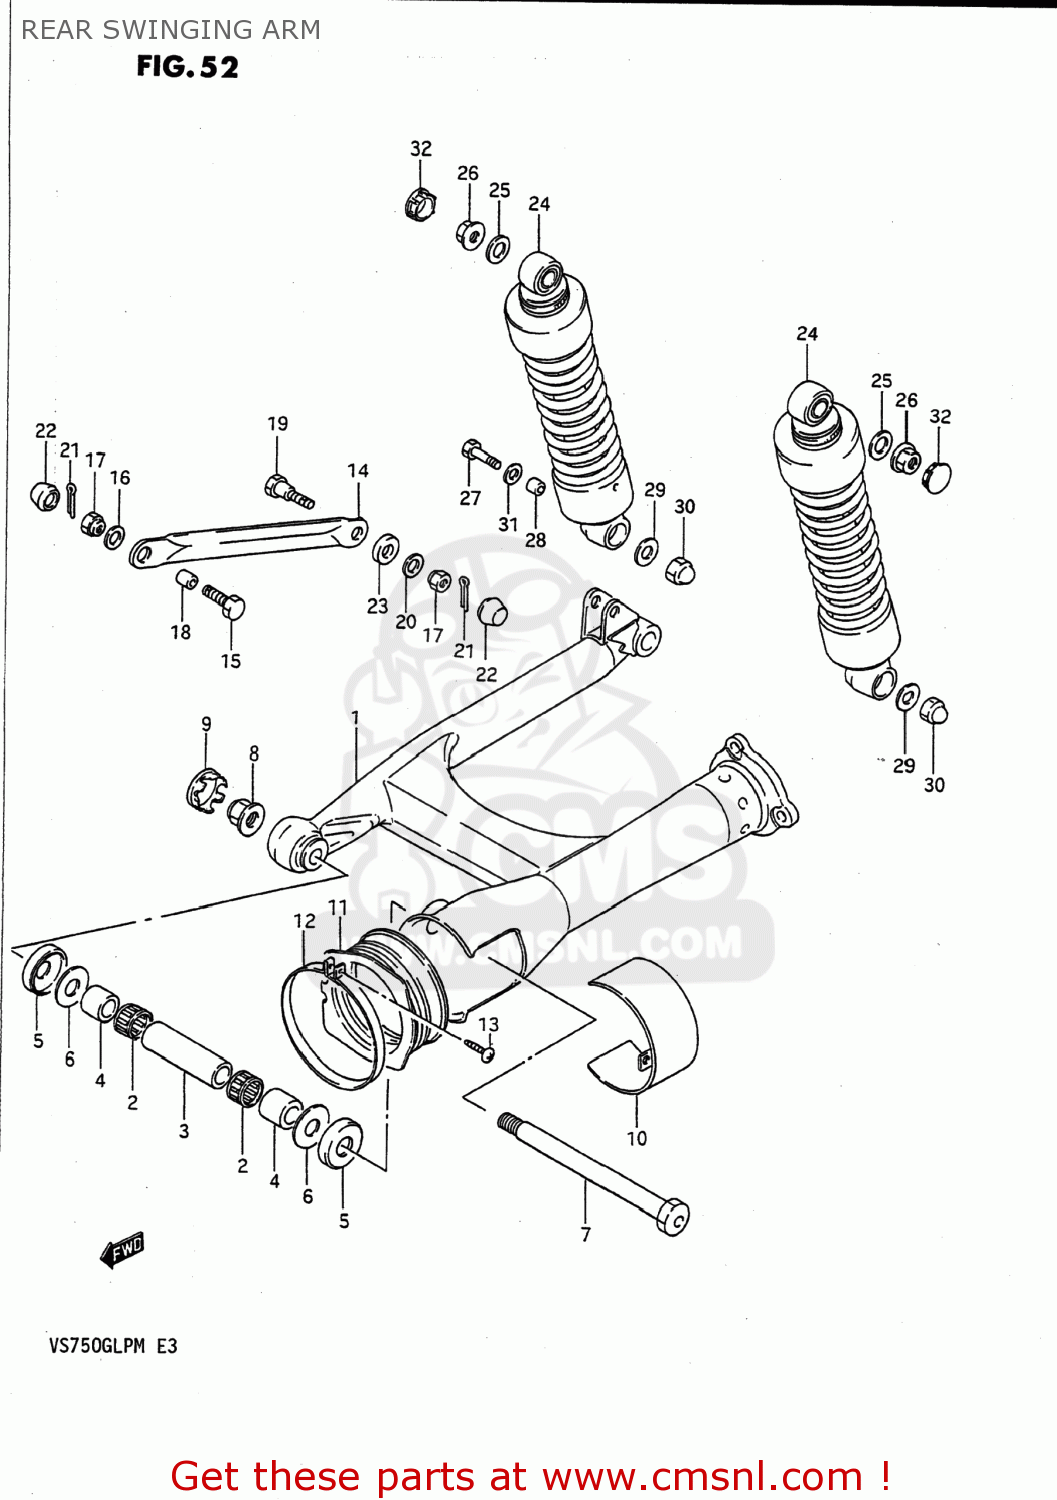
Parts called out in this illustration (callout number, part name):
1	SWING ARM COMP,REAR
2	BEARING(22X29X20)
3	SPACER,REAR SWING ARM PIVOT
4	SPACER,RR SWGARM PIVOT
5	CVR,RR SWGARM DUST SEAL(OD:40)
6	WASHER
7	SHAFT,RR SWINGINGARM PIVOT
8	NUT
9	CAP,RR SWINGING ARM PIVOT,R
10	COVER,REAR SWING ARM PIVOT
11	BOOT,PROPELLER SHAFT
12	CLAMP
13	SCREW 4X25
14	TORQUELINK,RR
15	BOLT(10X28)
16	WASHER
17	NUT
18	SPACER
19	BOLT(10X41)
20	WASHER (10X20X2.3)
21	COTTER PIN
22	CAP
23	CUSHION
24	ABSORBER ASSEMBLY,REAR SHOCK
25	WASHER
26	NUT
27	BOLT(10X39)
28	SPACER (10.2X14X20.7)
29	WASHER
30	NUT
31	WASHER 10MM
32	CAP,FRAME HANDLE GRIP
